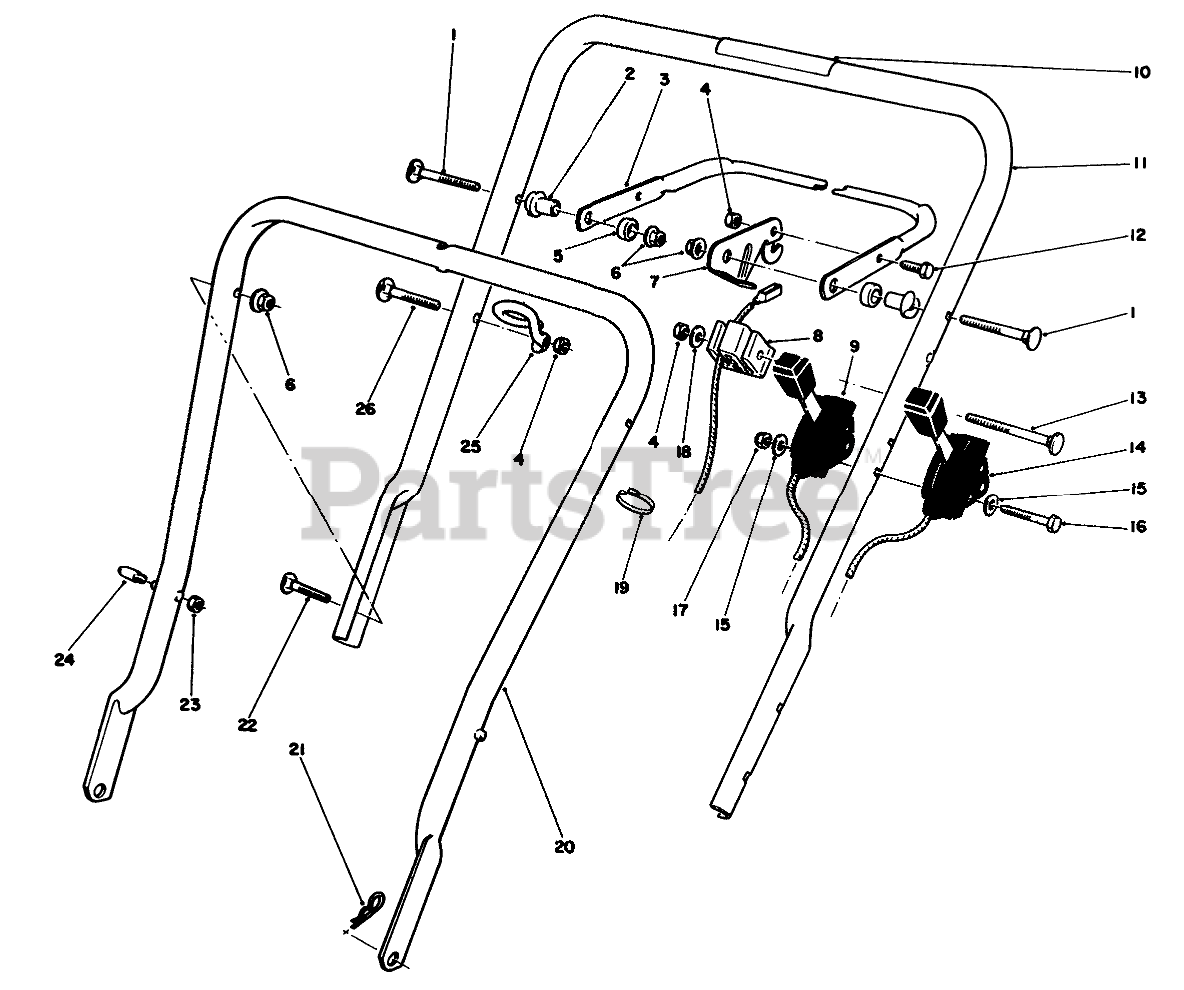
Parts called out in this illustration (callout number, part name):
1	5/16-18 X 2 HNDLE SCREW
2	SPACER-SUPPORT
3	Bar-Control
4	NUT-LOCK, NI
5	SPACER-NYLON
6	NUT-LOCK, NI
7	LEVER-CONTROL
8	SUPPORT-CABLE
9	THROTTLE CONTROL - R&S
10	WARNING DECAL
11	Handle-Upper (Incl Ref #10)
12	SCREW-HH
13	HANDLE SCREW
14	Control-Traction (Bend Type #3) Sheath Lg. 46")(Wire Lg. 2")
15	WASHER-FLAT
16	SCREW-SHH
17	NUT-LOCK, NI
18	WASHER-FLAT
19	TIE-CABLE
20	LOWER HANDLE ASM
21	PIN-COTTER, HAIR
22	SCREW
23	NUT-LOCK, NI
24	HANDLE PIN
25	Guide
26	HANDLE SCREW
